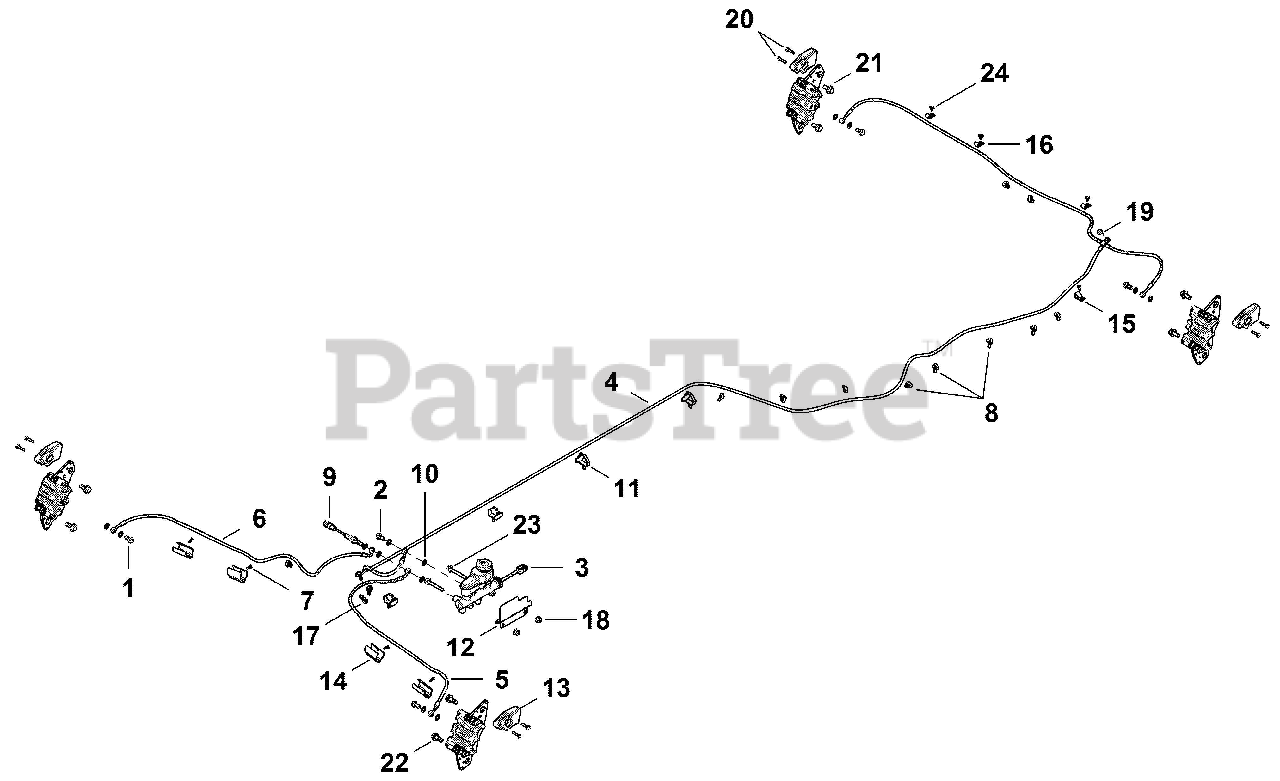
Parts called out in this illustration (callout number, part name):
1	BOLT-BANJO,10MMX1.00
2	BOLT-BANJO, 10MM X 1.25-6G
3	ASM-MASTER CYLINDER,UV,GS
4	LINE, BRAKE, 3 WAY
5	LINE, BRAKE, FRONT, LEFT
6	LINE-BRAKE,FRONT,RIGHT,BRD
7	POP RIVET(50)
8	CLIP-ROUTING
10	SEAL-STAT-O-3/8,70EP
11	CLIP-ROUTING
12	SHIELD-MASTER CYL
13	SCRAPER-BRAKE,FRONT
14	RETAINER-BRAKE LINE,1"
15	CLAMP, CABLE
16	CLAMP,HOSE
17	CLIP-ROUTING
18	NUT-M8X1.25,FLG,NYLOC-OLIVE D
19	SCR-M6X1.0X20,HXHD,FLG,TDFM,BL
21	BOLT-M10X1.25X20,HXFLG-OLV D
22	BOLT-M10X1.25X25,HXFLG,W/PATCH
23	SCR-HXFL-M8X1.25X60 8.8 ZOD
24	RIVET(50) *
